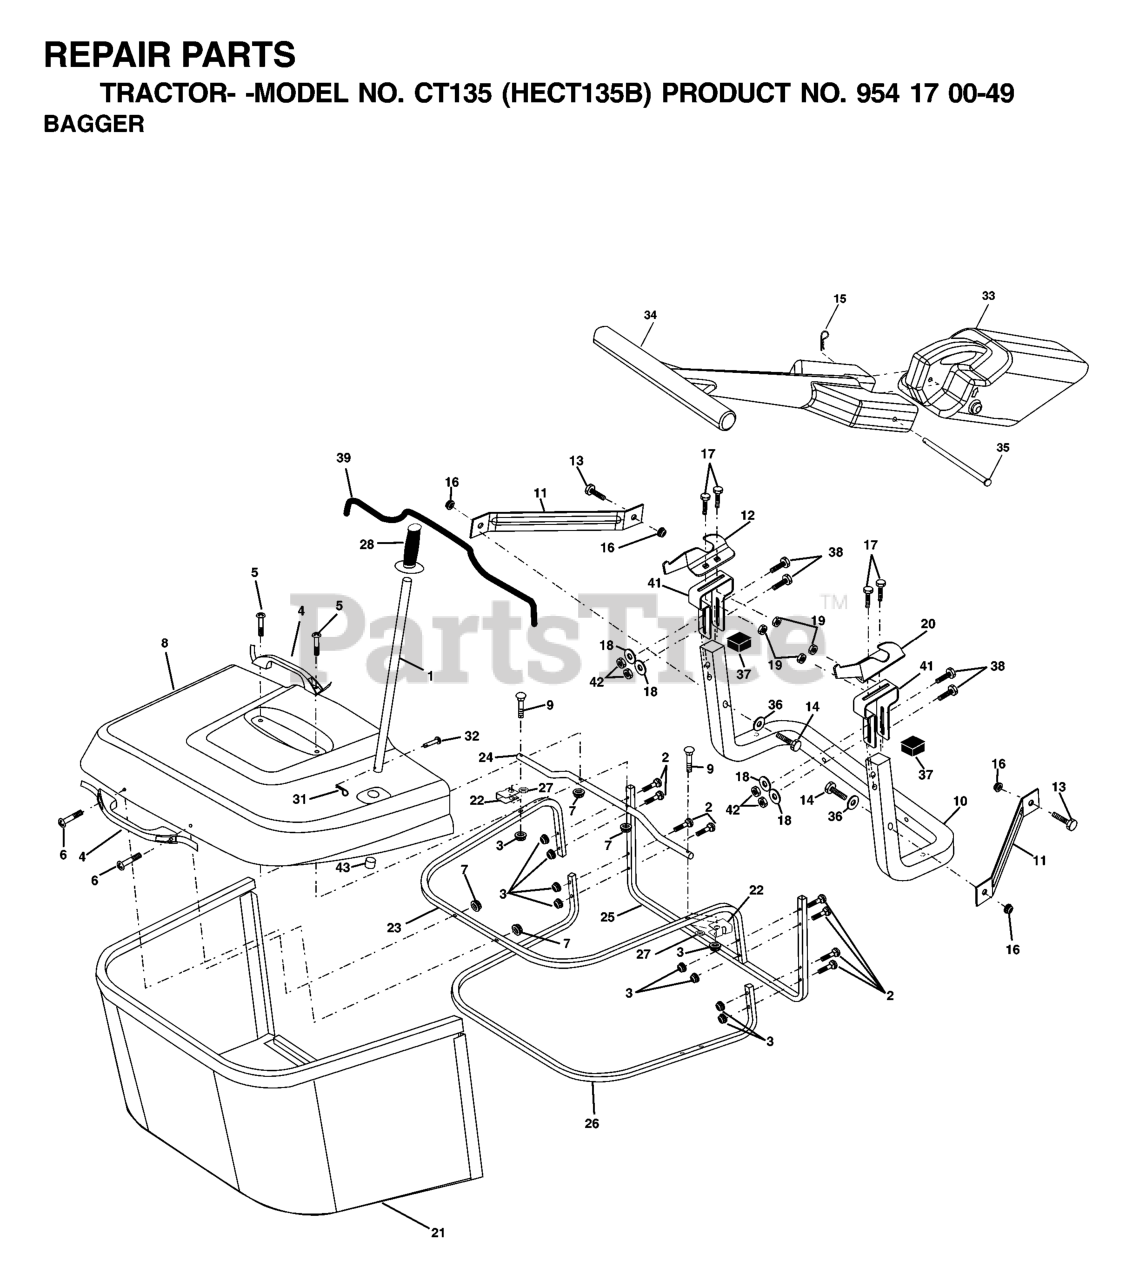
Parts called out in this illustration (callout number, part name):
1	TUBE HANDLE
2	Bolt Carriage 1/4-20 x 2.0 Gr.5
3	NUT T
4	HANDLE.BAGGER.W/LVRS.BLK.CRD
5	SCREW.PAN.HEAD
6	REPL BY 532 75 00-29
8	COVER.PNT.BGR.CRD.WSLOTS.MS668
9	Bolt Carriage 1/4-20 x 2.25d x Gr.5
10	TUBE
11	BRACKET.SUPPORT.UPPER.BAG.CRD
13	BOLT
14	BOLT-HEX EAK
15	RETAINER-SPRNG RB
16	NUT LOCK FLG 3/8-16 UNC
17	RP BOLT 5/16-18 X3/4 ZN/YEL GR
18	WASHER M
19	NUT LOCK HEX FLANGE 5/16-18
20	BRACKET
21	GRASS BAG
22	BRKT.SIDE.BAG.CRD
23	TUBE.UPPER.BAG.CRD
24	TUBE.PIVOT.BAG.CRD.BLACK
26	TUBE.LOWER.BAG.CRD
28	GRIP.HANDLE.BLACK
31	RETAINER M
32	RIVET,DRILLED
33	PLUG.MULCHER.92 CRD
34	HANDLE.MULCHER.92.CRD (2 2)
36	WASHER
37	Plug Support Bagger CRD
38	BOLT.5/16-18X2.5
39	SEAL.TRIM.37'
41	BRKT.VERT.ADJ.BAGGER.CRD
42	NUT.71038.31-18.HEX.NYLOCK
43	PLUG, TUBING END
